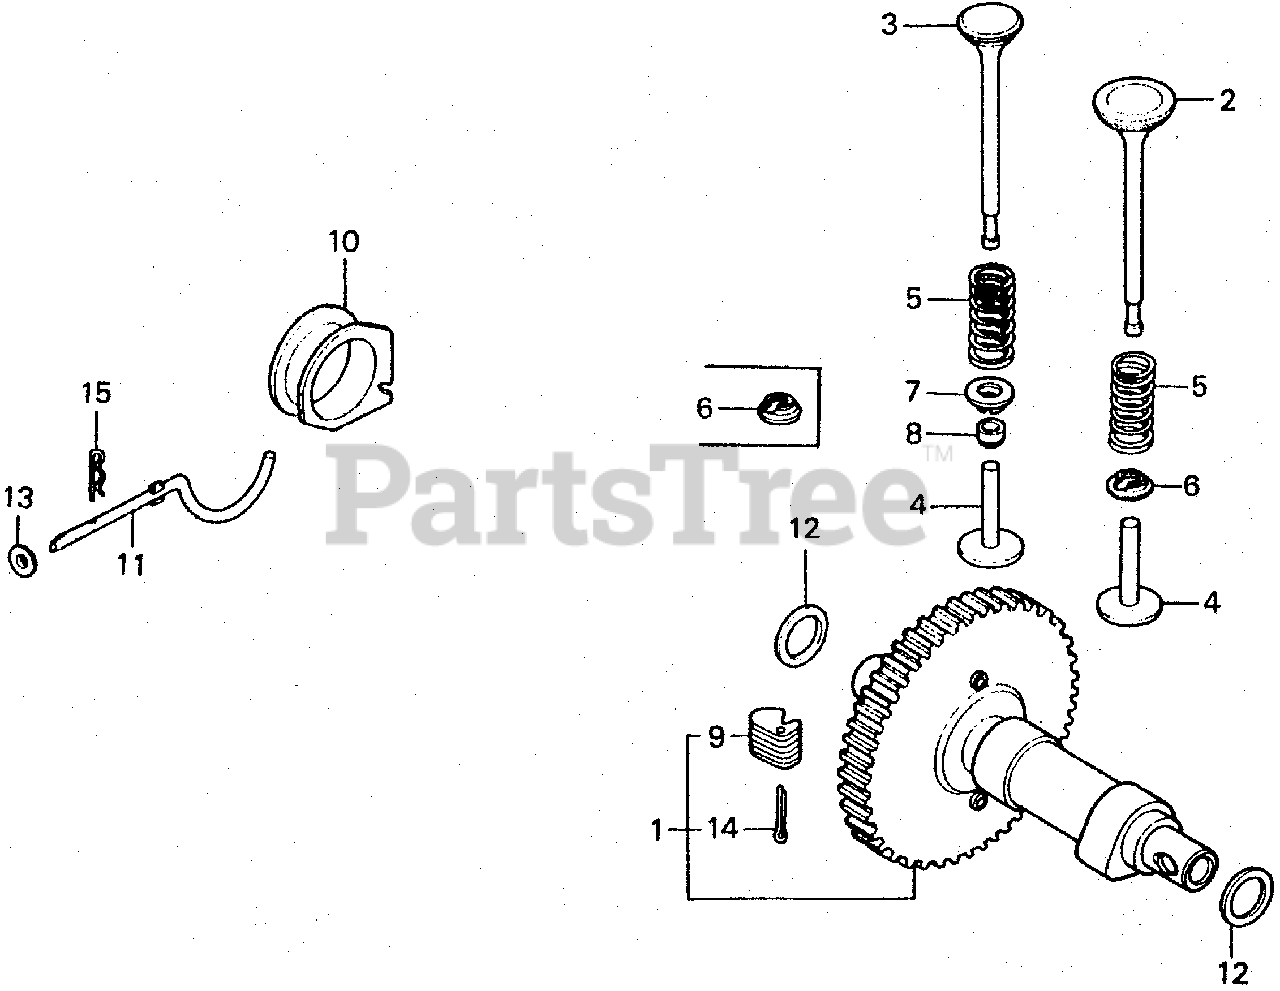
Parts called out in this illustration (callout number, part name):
1	CAMSHAFT ASSY.
2	VALVE, IN.
3	VALVE, EX.
4	LIFTER, VALVE (45.89MM)
4	LIFTER, VALVE (46.04MM)
4	LIFTER, VALVE (46.19MM)
4	LIFTER, VALVE (46.34MM)
5	SPRING, VALVE
6	RETAINER, VALVE SPRING
7	RETAINER, VALVE SPRING
8	ROTATOR, EX. VALVE
9	WEIGHT, GOVERNOR
10	SLIDER, GOVERNOR
11	SHAFT, GOVERNOR
12	WASHER, THRUST (18MM)
13	WASHER, PLAIN (6MM)
14	PIN, SPLIT (3.0X45)
15	PIN, LOCK (10MM)
